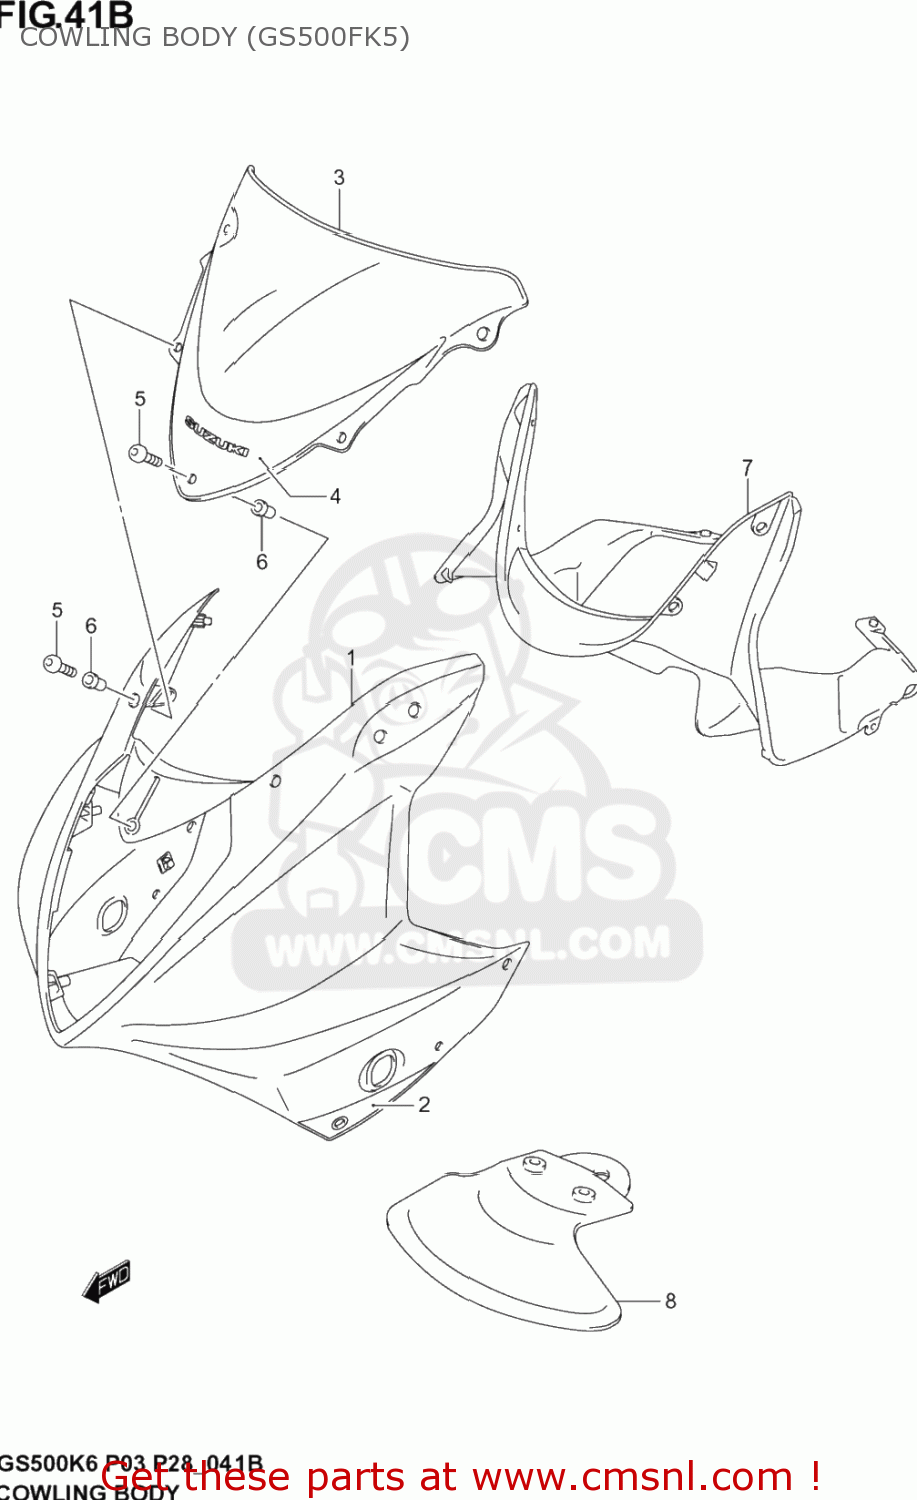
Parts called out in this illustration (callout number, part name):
1	COWLING BODY B
2	TAPE SET,SIDE
3	WINDSCREEN
4	TAPE,WINDSCREEN
5	SCREW(5X18)
6	NUT
7	PANEL, FRONT
8	COVER,LOW.BRAC
